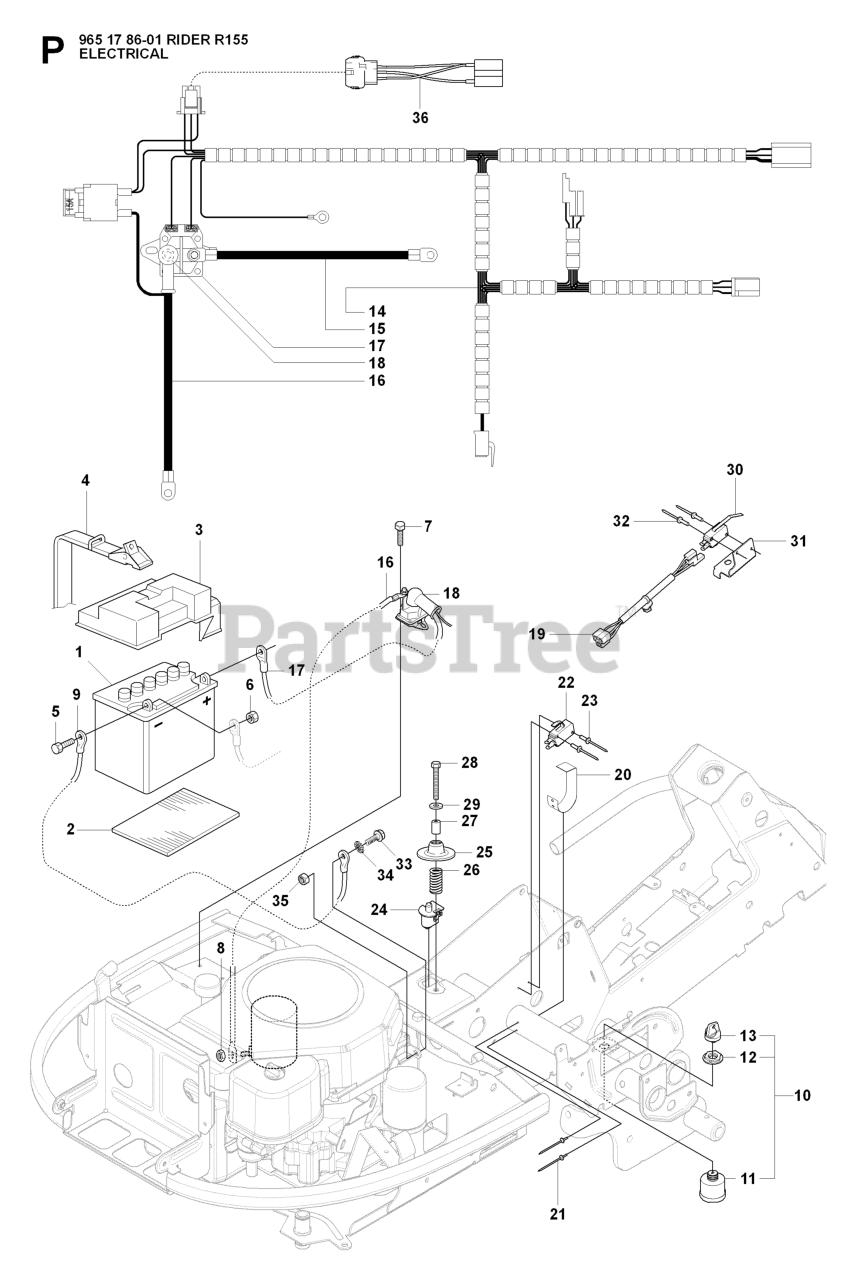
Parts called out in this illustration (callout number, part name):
1	BATTERY - DRY
10	IGNITION SWITCH
11	IGNITION SWITCH
13	IGNITION KEY
19	WIRING
22	%BRAKER
27	SPACER TUBE
28	SCREW
29	WASHER BRB 8.4X17
30	RP MICRO SWITCH
35	NUT
